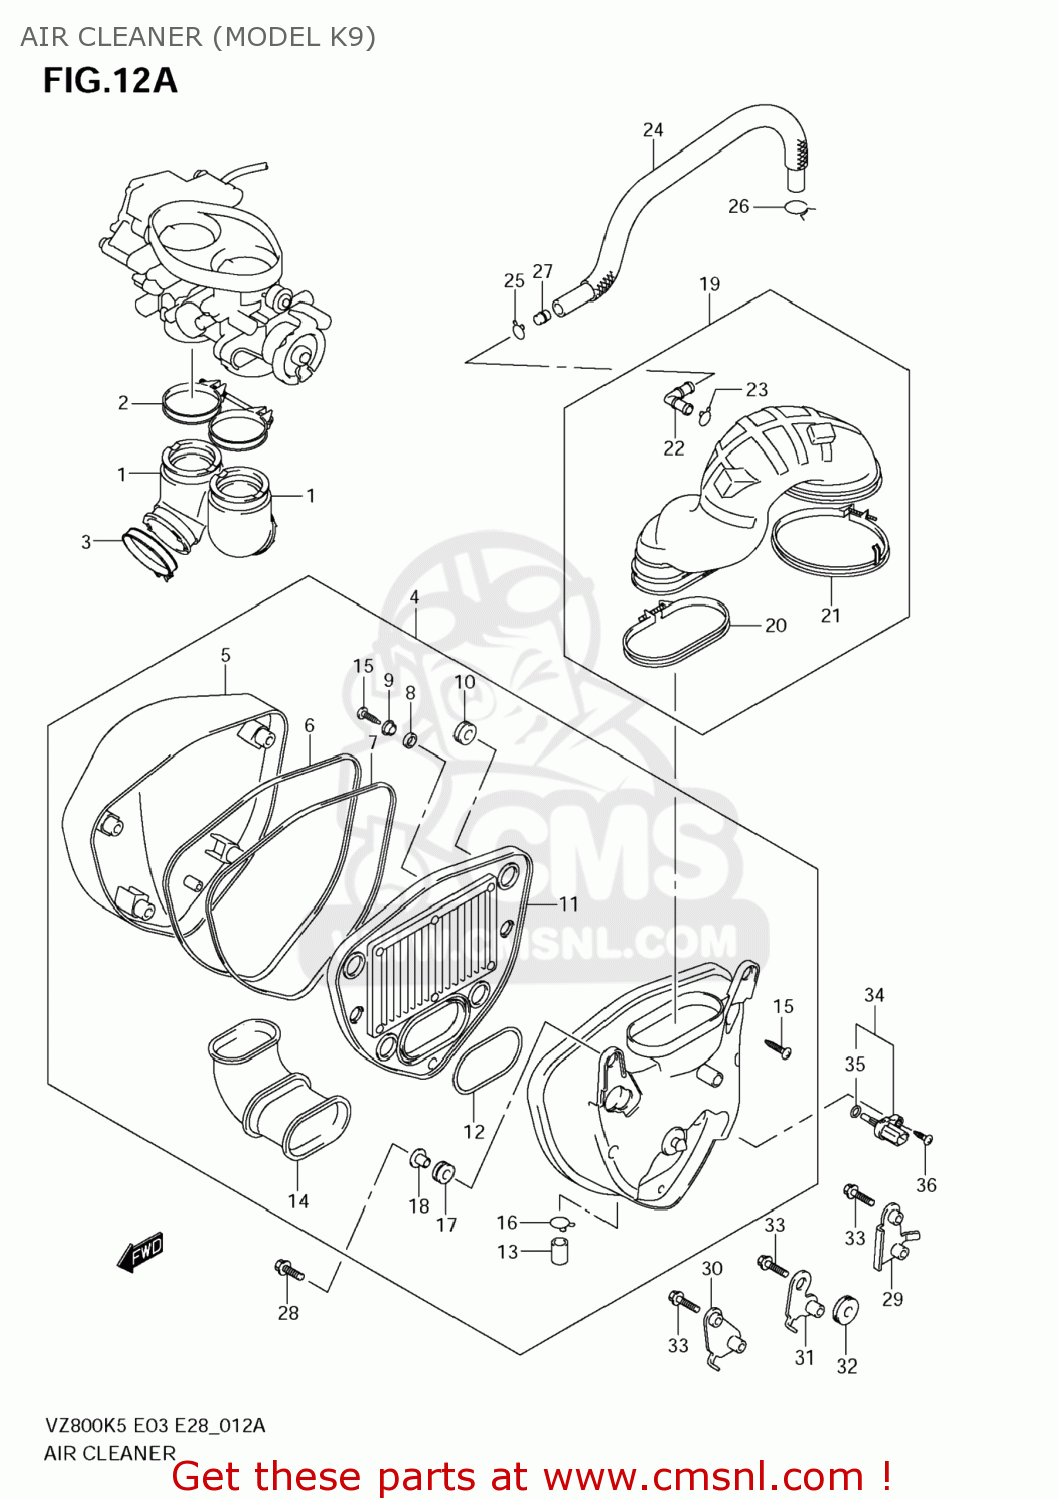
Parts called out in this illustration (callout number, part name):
1	PIPE,INTAKE
2	CLAMP,INTAKE PIPE
3	CLAMP,INTAKE PIPE
4	CASE ASSY,AIR CLEANER
5	CAP,AIR CLEANER
6	GASKET (NAS)
7	GASKET (NAS)
8	CUSHION
9	WASHER
10	CUSHION
11	FILTER,AIR CLEANER
12	GASKET,FILTER (NAS)
13	PLUG
14	TUBE,INLET
15	SCREW
16	CLIP
17	CUSHION
18	COLLAR,CLEANER CASE
19	TUBE ASSY,OUTL
20	CLAMP
21	CLAMP
22	JOINT
23	CLIP
24	TUBE,BREATHER
25	CLIP
26	CLAMP
27	JET,BREATHER
28	SCREW(6X20)
29	BRACKET,AIR CLEANER NO.1
30	BRACKET,AIR CLEANER NO.2
31	BRACKET,AIR CLEANER NO.3
32	CUSHION
33	BOLT
34	SENSOR,AIR TEMP
35	O RING
36	SCREW
